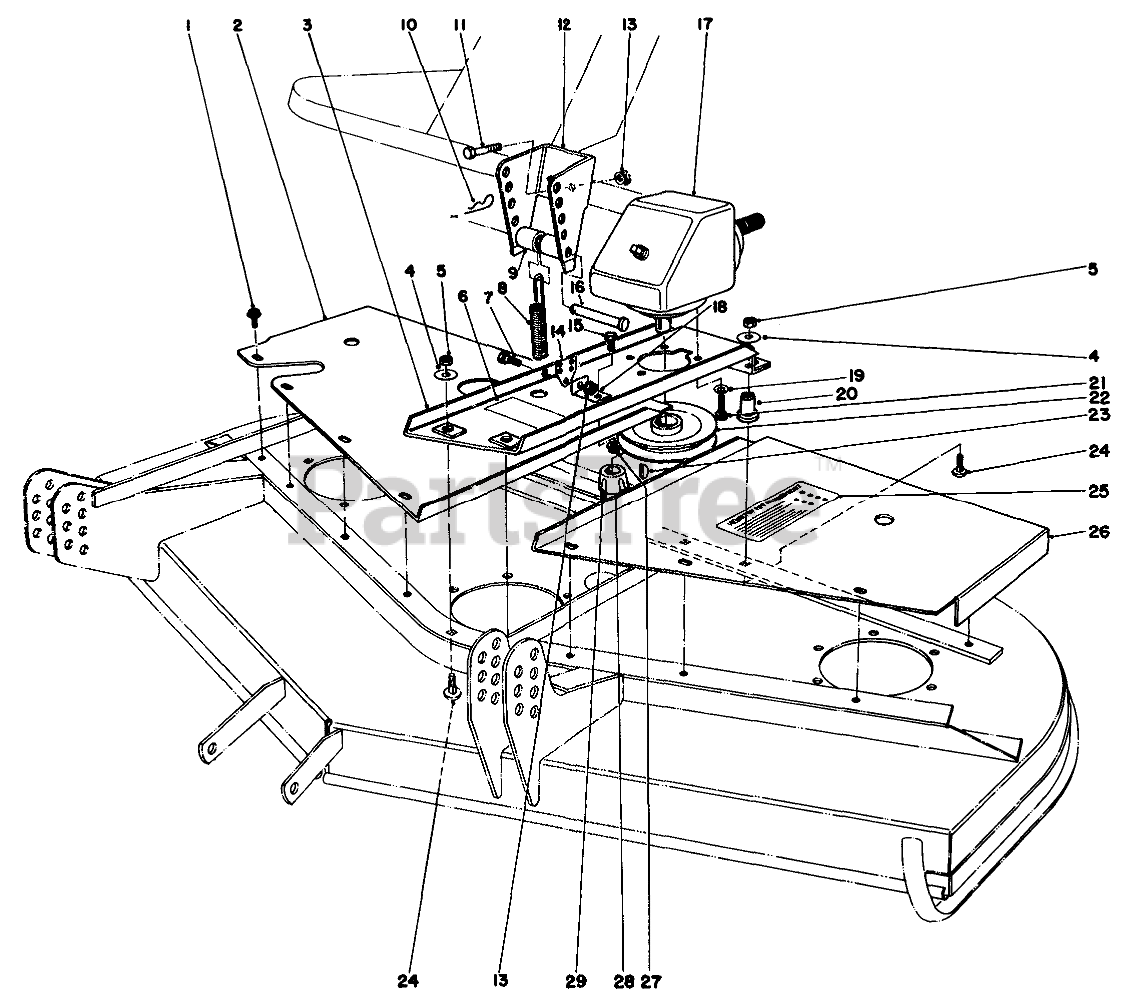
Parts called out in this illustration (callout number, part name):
1	SCREW-HHFTF
2	RH COVER WA R
3	GEARBOX BASE WA R
4	WASHER
5	NUT-HEX
6	Decal-Caution
7	BOLT-SHOULDER
8	Spring-Extension
9	SPACER
10	PIN-HAIR
11	SCREW-HH
12	SPRING BRACKET R
13	NUT-HHF, WHIZ
14	SPRING END R
15	SCREW-HH
16	PIN-CLEVIS
17	Gear Box
18	EXTENSION BRKT R
19	WASHER-LOCK
20	MOUNT
21	SCREW-HSH
22	PULLEY
23	KEY-WOODRUFF
24	SCREW-CARR
25	DECAL
26	LH COVER WA R
27	NUT-HF
28	BUSHING-LOCK, TAPER
29	SCREW-SET, HSH
